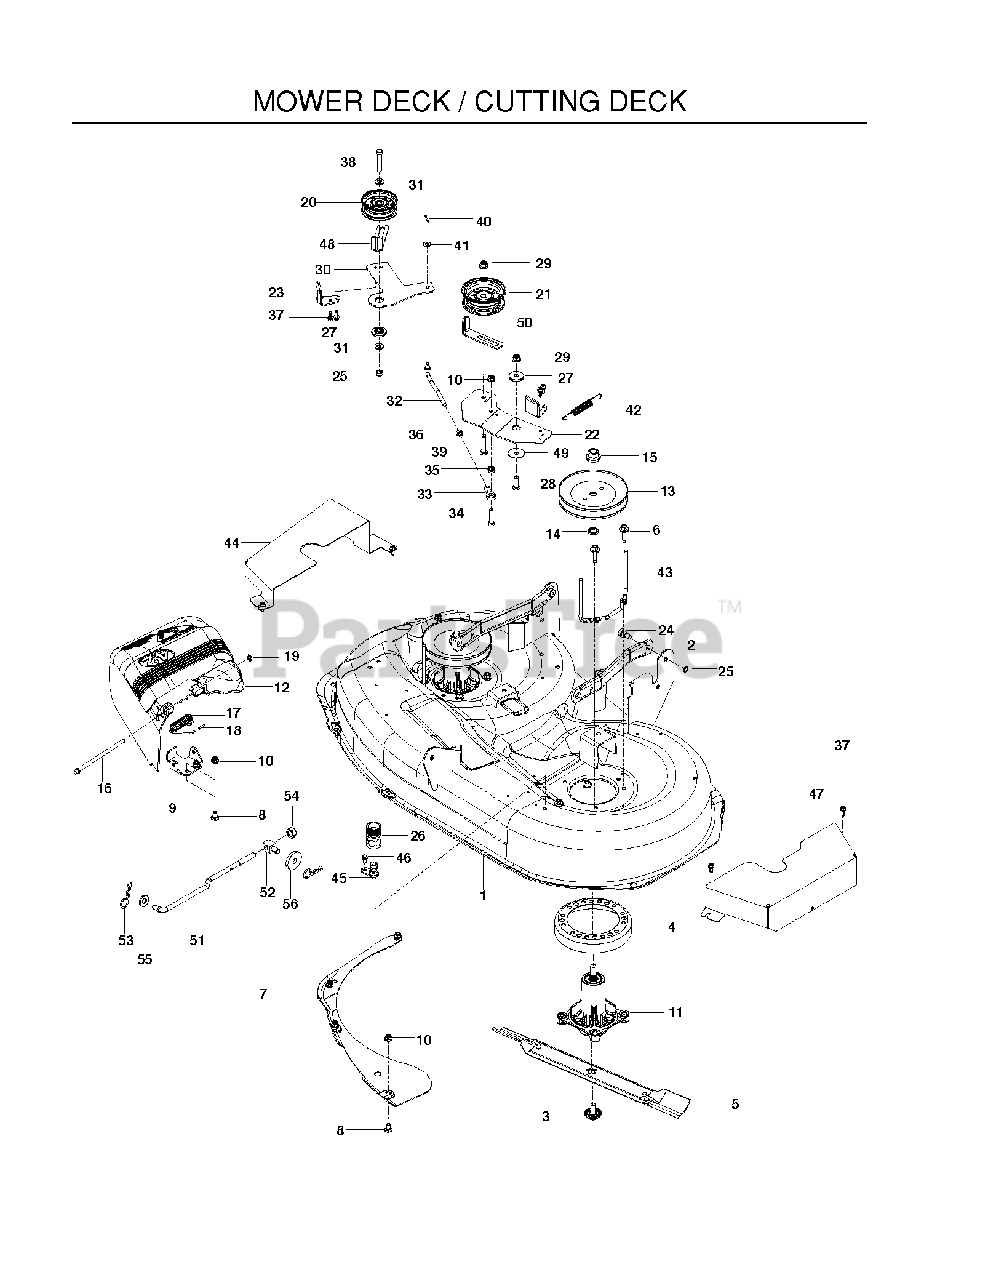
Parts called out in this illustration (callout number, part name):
1	DECK.STMP.W/DECALS.42.BLUE.DIX
2	ARM.SUSPENSION.MOWER
3	BOLT.WASHER.ASM.7/16-2
4	STRIPPER-ROUND-UNIVERSAL
5	BLADE.42".MULCH
6	WASHER HEAD SCREW
7	BAFFLE VORTEX 42
8	CARRIAGE BOLT 5/16C X 5/8"
9	BRKT.DEFLECTOR.38"2005+
10	5/16-18 NYLOC FLANGE NUT
11	MANDREL.ASM.SUB-NON.GR
12	DEFLECTOR 42
13	PULLEY.MANDREL.5.438.P
14	WASHER-SPACER
15	LOCKNUT - 9/16
16	ROD, HINGE
17	SPRING, TORSION DEFLECTOR
18	CAP-SLEEVE
19	PUSH NUT
20	IDLER PULLEY
21	PULLEY.IDLER.FLAT
22	ARM.IDLER.BLACK
23	ARM, LH BRAKE
24	SB 3/8-16 X 3/8 SKT HD ZD
25	NUT HEX 3/8-16 NYLON, THIN
26	COUPLING.QUICK CONNECT
27	SPACER.RETAINER
28	HCS 3/8C X 1
29	NUT 3/8-16 HEX FLG NYLOC ZD
30	ARM.BRAKE.42.BLACK
31	WASHER 3/8 SAE FLAT
32	LINKAGE, DECK BRAKE
33	BALL JOINT, RIGHT HANDED
34	CAPSCREW 5/16 X 1/1/2 HEX HEAD
35	NUT 5/16C WHIZ
36	NUT 5/16C HEX
37	SCREW- 1/4-20 X 5/8
38	HCS 3/8C X 2
39	HCS 3/8-16 X 1 3/4 GR5
40	COTTER PIN 1/8 X 3/4
41	FLAT WASHER 5/16 SAE
42	SPRING RETURN
43	KEEPER, MANDREL BELT
44	GUARD.RIGHT.BELT.42"BLACK
45	PORT.WASHOUT
46	BOLT 1/4-20 X 1/2 HWST
47	GUARD.LEFT.BELT.42" BLACK
48	GUIDE, BELT
49	WASHER, FRICTION
50	GUIDE, BELT
51	LINK LIFT SUSP. FRONT MOWER
53	HAIRPIN #4
54	NUT, 7/16-20 HEX NYLOC ZC
55	WASHER 1/2" FLAT
56	SPINDLE WASHER
